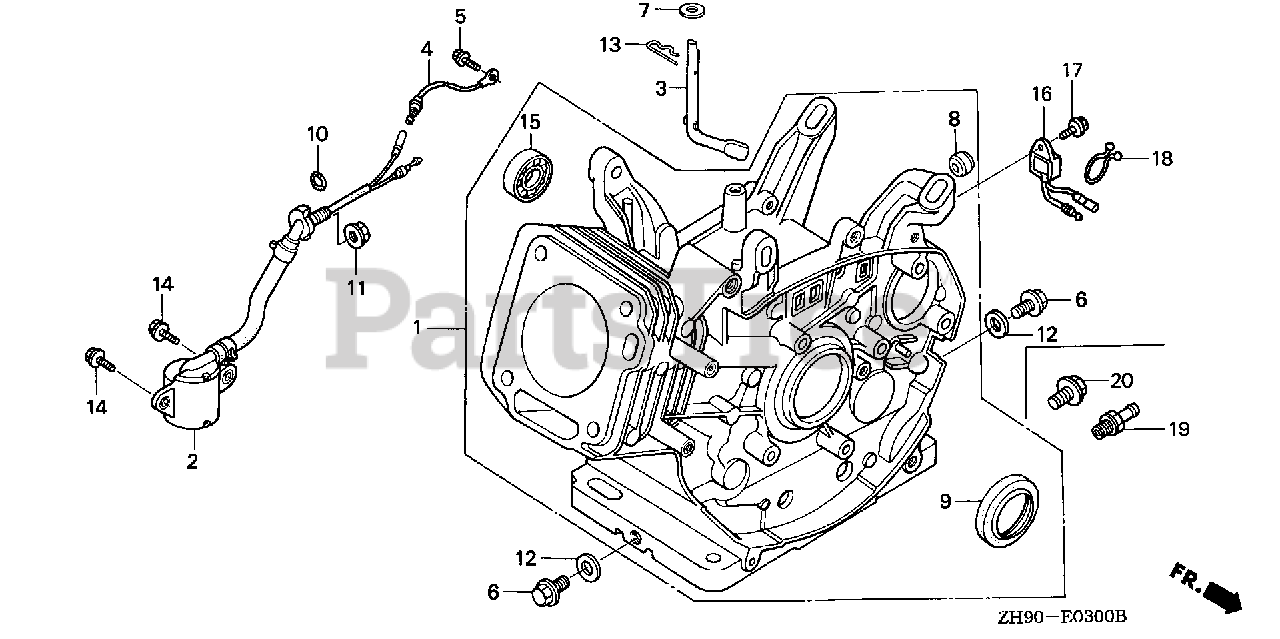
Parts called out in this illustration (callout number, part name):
1	CYLINDER ASSY. (BALANCER+ALERT)
2	SWITCH ASSY., OIL LEVEL
3	SHAFT, GOVERNOR ARM
6	BOLT, DRAIN PLUG (12X15)
7	WASHER (8.2X17X0.8)
9	OIL SEAL (30X46X8)
10	O-RING (14MM) (ARAI)
10	O-RING (14MM) (NOK)
11	NUT, FLANGE (10MM)
12	WASHER, DRAIN PLUG (12MM)
13	PIN, LOCK (10MM)
14	BOLT, FLANGE (6X12)
15	BEARING, RADIAL BALL (6202)
16	ALERT UNIT, OIL
17	BOLT, FLANGE (6X12) (CT200)
